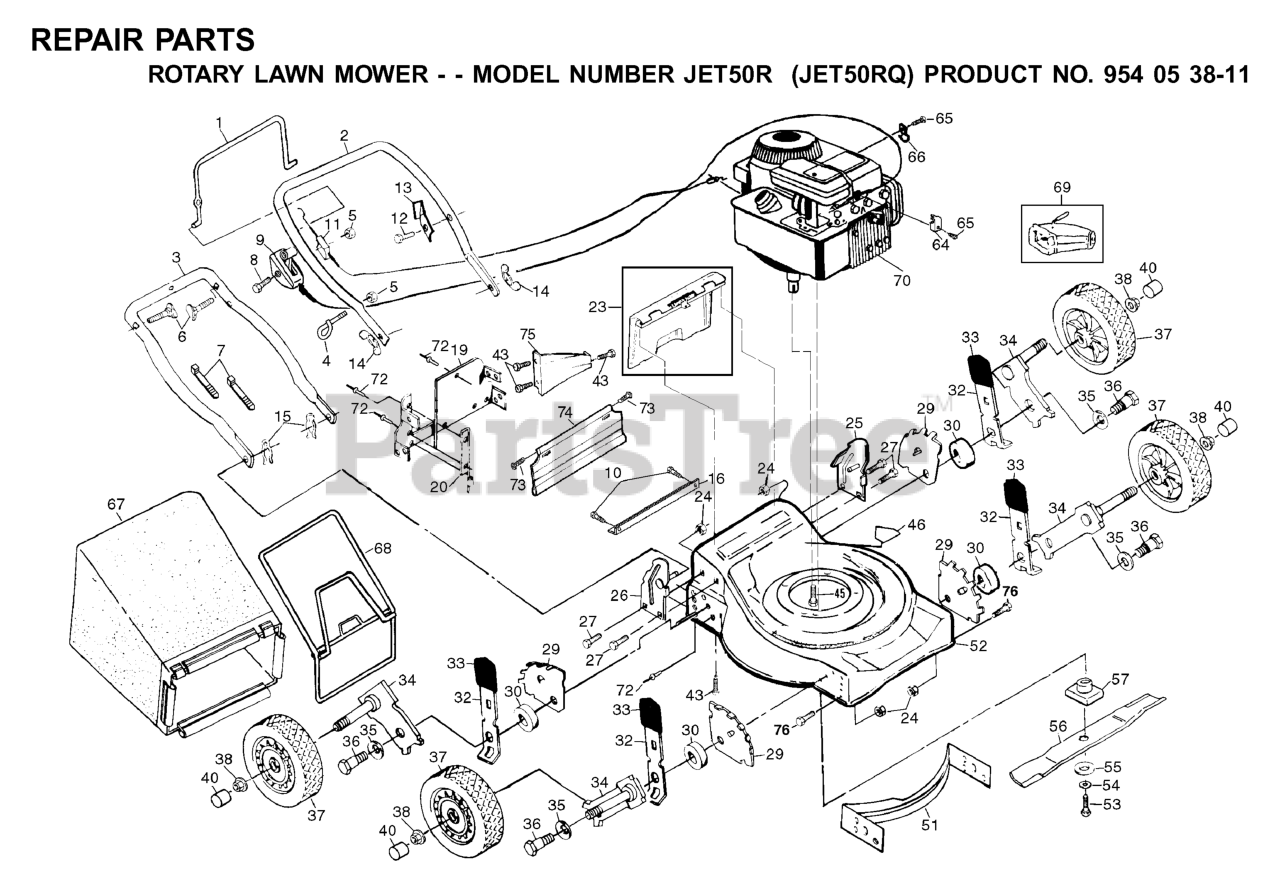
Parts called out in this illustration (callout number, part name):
1	CONTROL BAR
2	UPPER HANDLE
3	HANDLE
4	ROPE GUIDE
5	NUT
6	HANDLE BOLT
7	TIE GUIDE
8	SCREW.PAN.HEAD
9	THROTTLE CONTROL
11	CABLE.MZR.51.RT.SP./PU.
12	TAPPING SCREW
13	BRACKET UPSTOP
14	NUT WING PM
15	HAIRPIN COTTER
16	REPL BY 532 14 61-43
20	SIDE BAFFLE
23	REAR DOOR ASSEMBLY KIT
24	LOCKNUT PM
25	HANDLE BRACKET ASSEMBLY - LEFT
26	HANDLE BRACKET ASSEMBLY-RIGHT
27	SELF-TAPPING SCREW 5/16-18X3/4
29	WHEEL ADJUST BRACKET
30	RP SPACER HT ADJ
32	SELECTOR SPRING
34	AXLE, REAR
35	WASHER.BELLEVILLE (3 2 LB)
36	BOLT
37	WHEEL
38	HEX FLANGE LOCKNT
45	BOLT 3/8-16X1-1/8
46	DECAL MOWER CUT/FINGER
53	SCREW, HEX HD 3/8-24 X 1-3/8
54	LOCKWASHER
55	WASHER,HARDEN
56	20" Blade
57	BLADE ADAPTOR
64	WASHER
65	SCREW.HEX.HEAD.WASHER.10-16
66	GUIDE CLIP PM
68	CATCHER.FRAME.WALK
72	RIVET BLIND
73	HINGE SCREW
74	REAR SKIRT
76	SCREW 1/4X20
